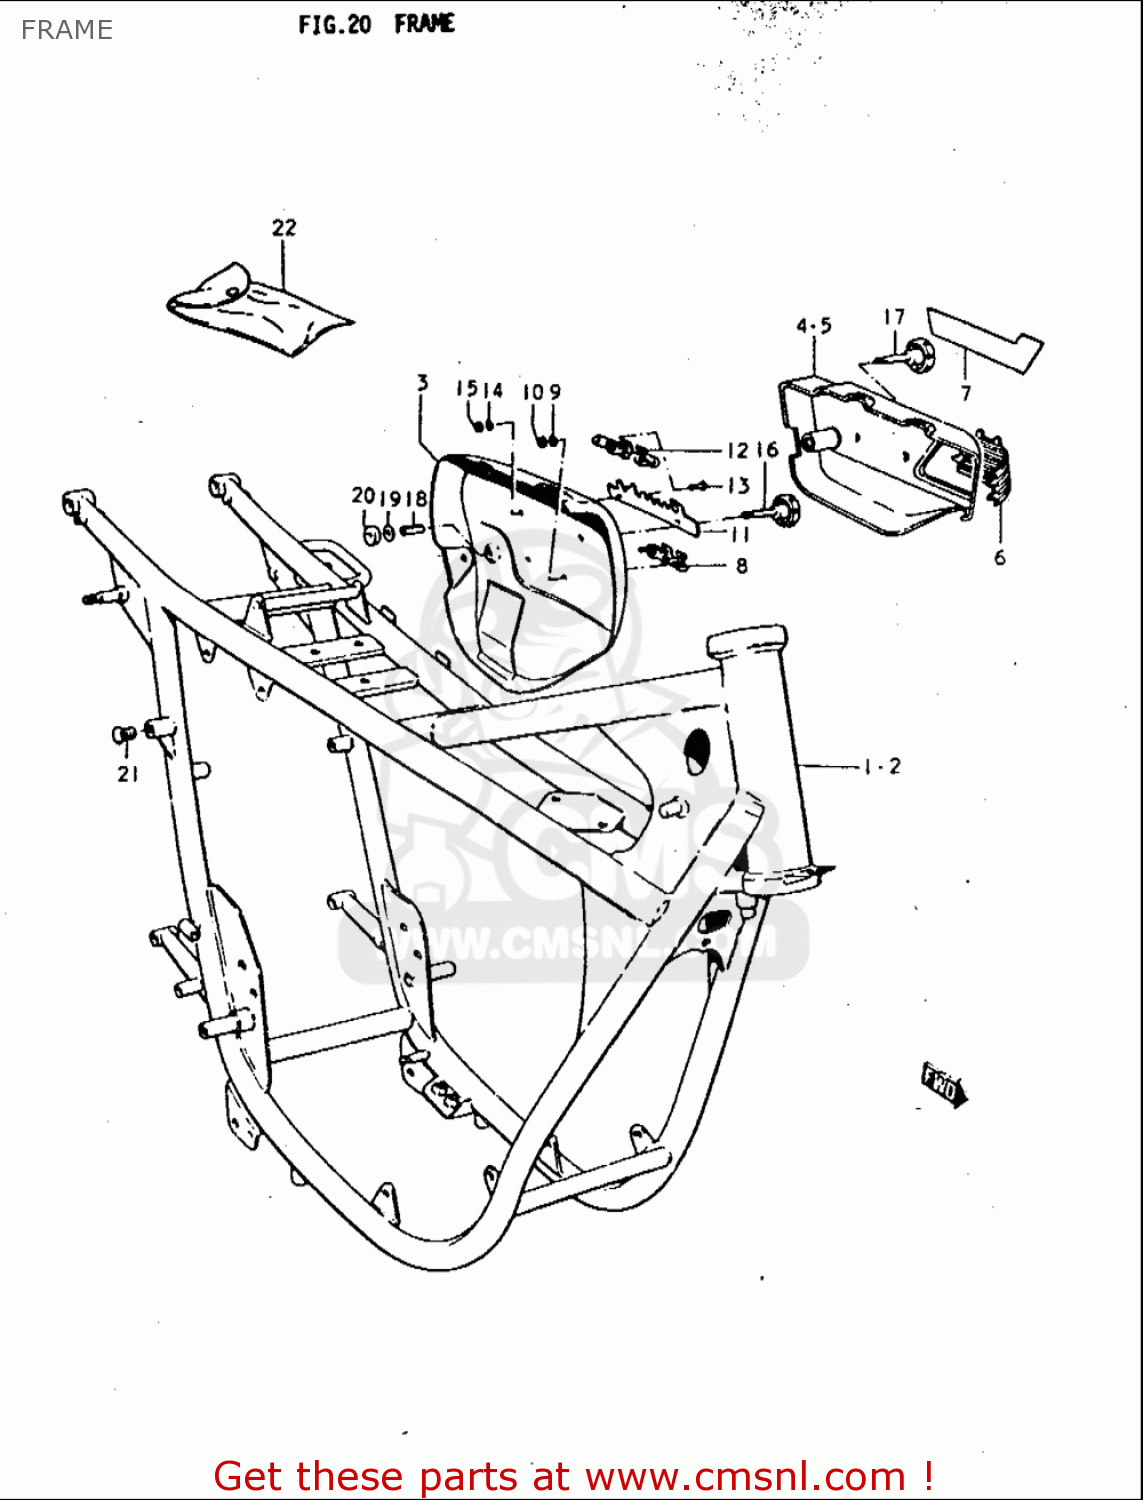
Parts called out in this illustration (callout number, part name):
9	WASHER,LOCK
10	NUT
14	WASHER,LOCK
15	NUT
19	NUT
20	WASHER
21	CAP(OD:14)
